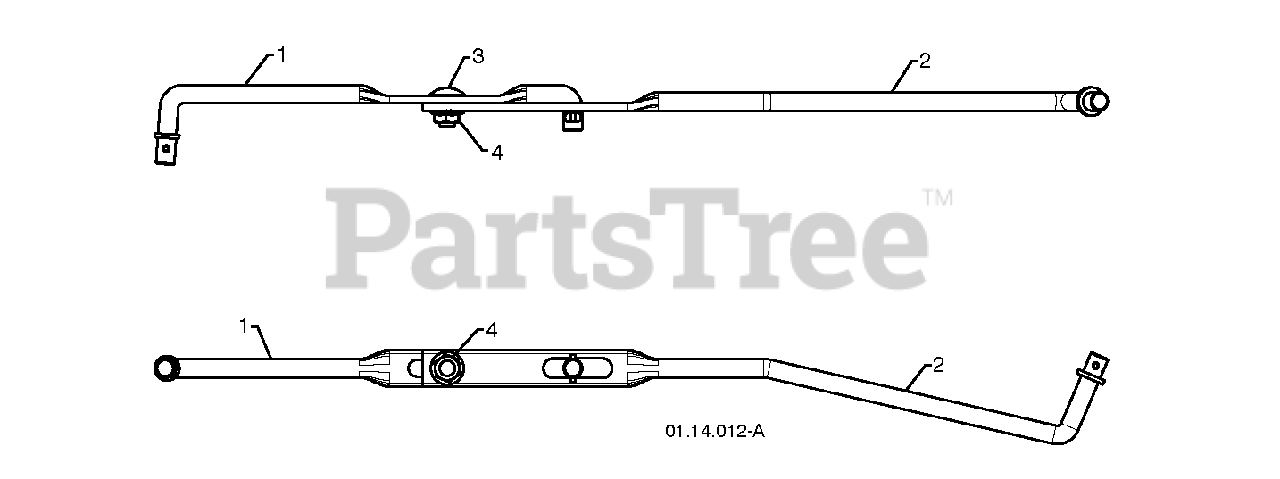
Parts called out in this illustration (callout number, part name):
1	ROD, UPPER SPEED CONTROL
2	ROD, LOWER SPEED CONTROL
3	BOLT
4	NUT.FLANGE.5/16
